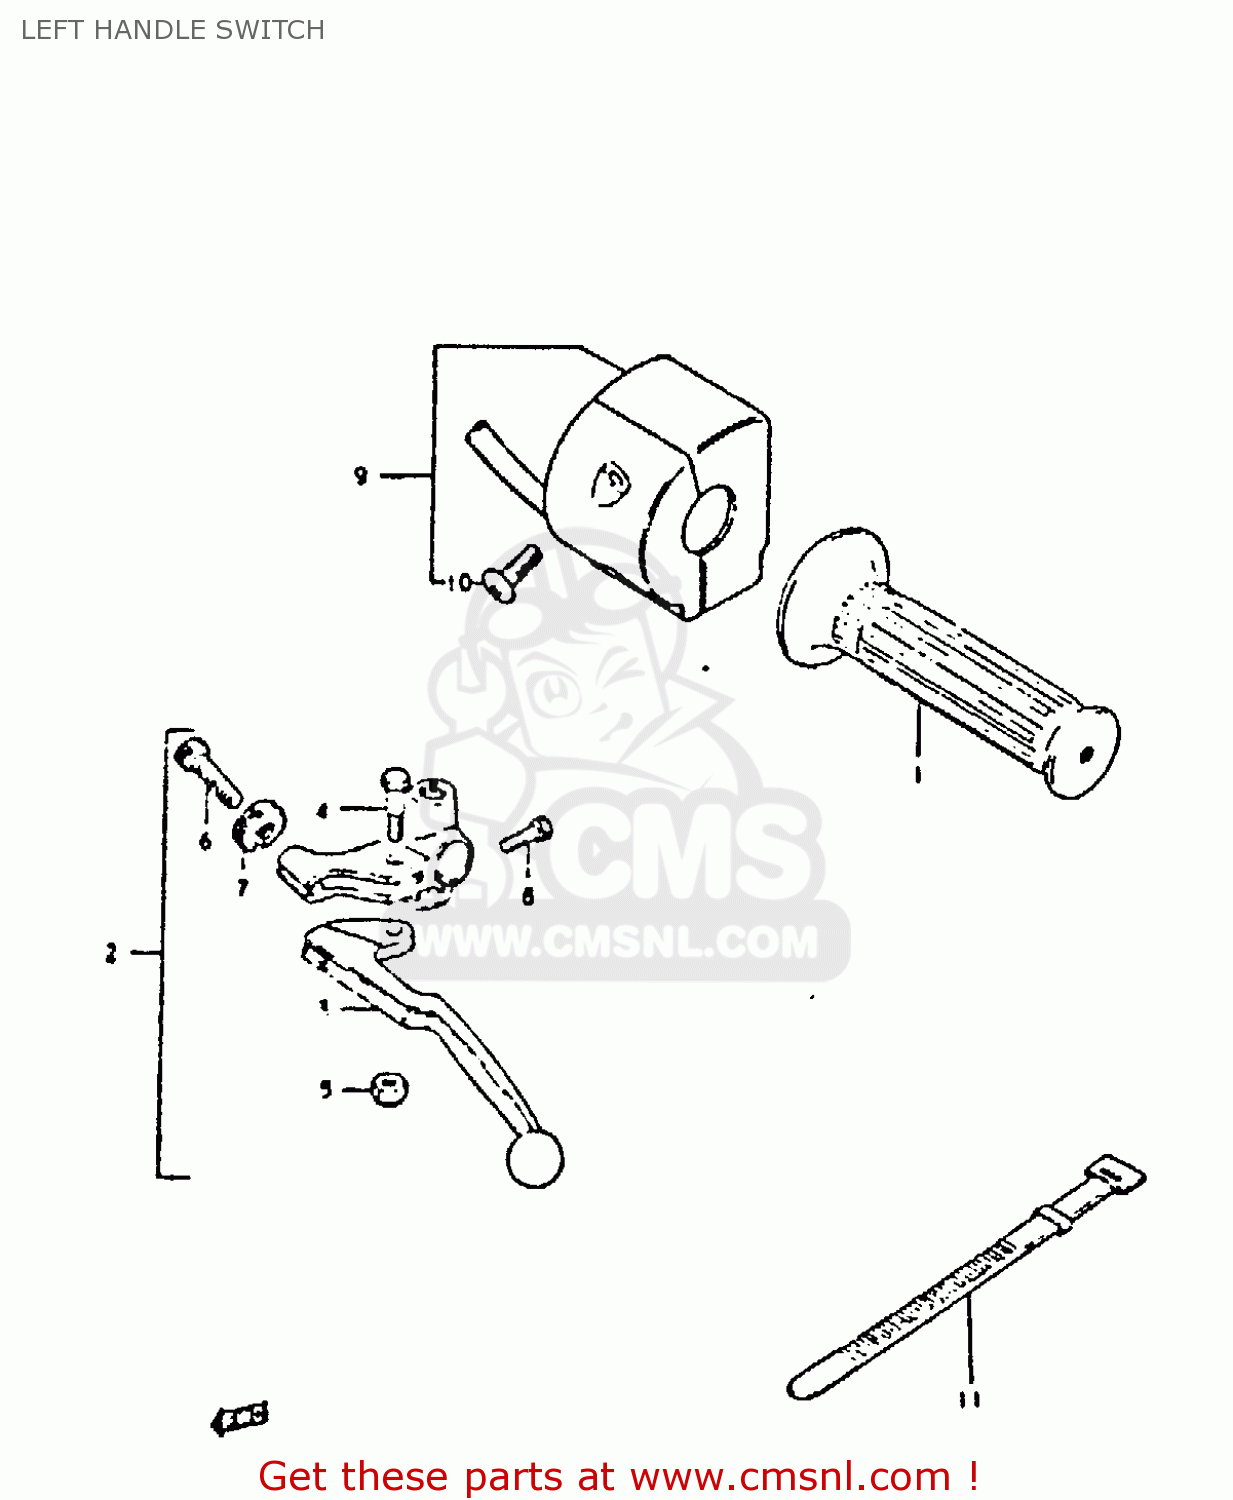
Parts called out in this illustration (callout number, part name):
1	GRIP,LEFT
2	LEVER ASSY, CLUTCH
3	LEVER,CLUTCH
4	BOLT,LEVER
5	NUT 6MM
6	ADJUSTER,CABLE
7	NUT,CABLE ADJUSTER
8	BOLT
9	SWITCH ASSY, HANDLE LH
10	SCREW
11	CLAMP(L:120)
